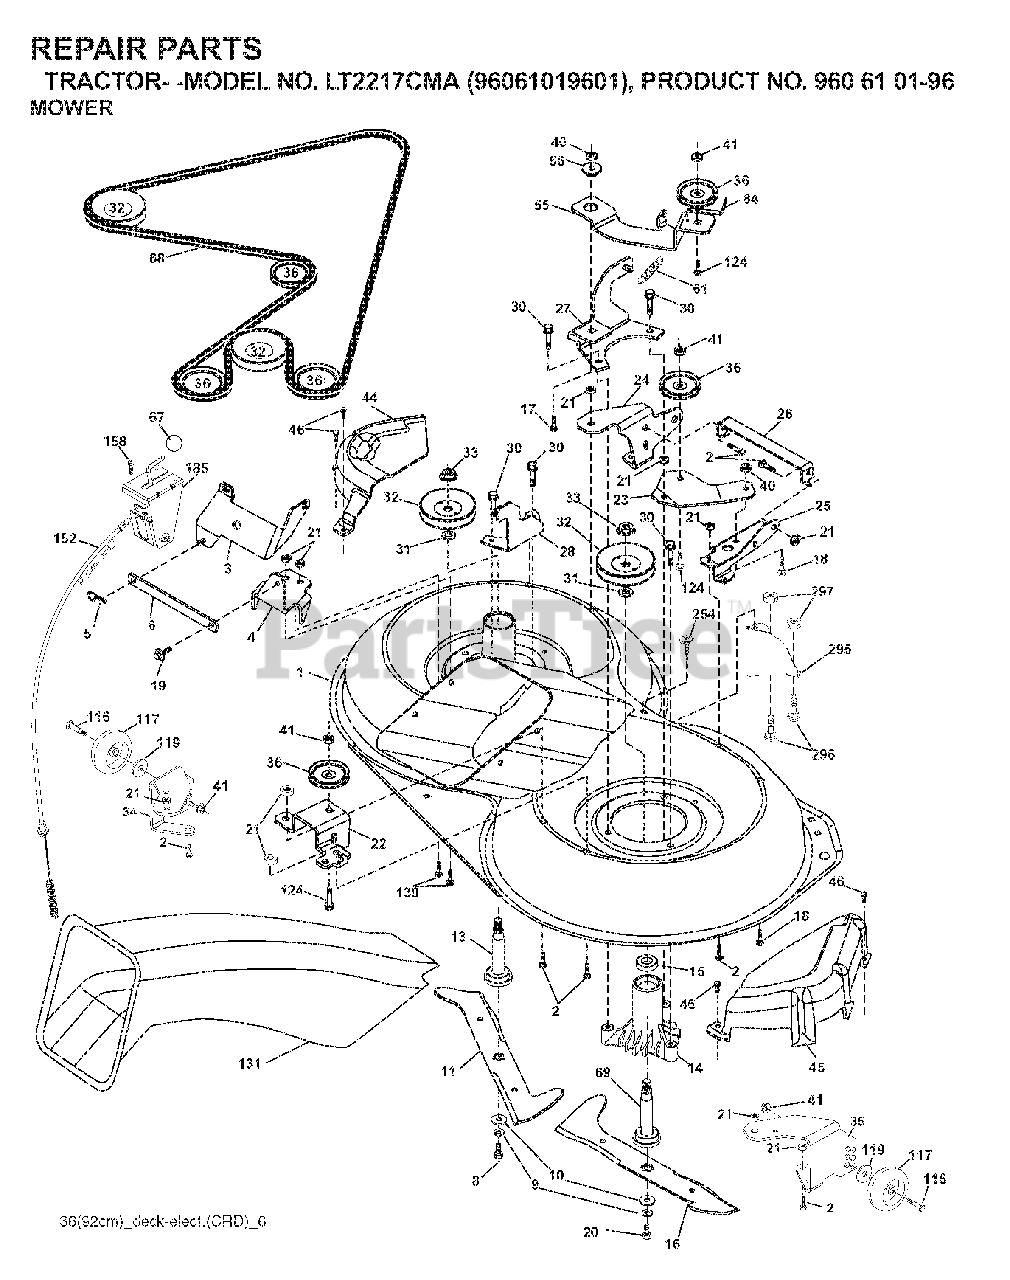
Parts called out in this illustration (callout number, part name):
2	BOLT
3	BRACKET
5	RETAINER-SPRNG RB
6	BAR SWAY
9	LOCKWASHER
10	WASHER.BLADE
13	SHAFT ASM VENT
14	HSG MANDREL
17	BOLT.3/8-14X1.25
19	BOLT SHD 5/16-18
21	LOCKNUT
24	BRACKET
25	BRACKET
28	BRACKET
30	SCREW, WASHER HEAD
31	WASHER.SPACER.MANDREL
32	PULLEY MANDREL
33	NUT.FLANGE.LOCK.TOP
36	PULLEY.IDLER.4.25
40	LOCKNUT
41	NUT LOCK FLG 3/8-16 UNC
45	MANDREL COVER
46	SCREW.1/4-20X5/8
56	SPACER.RETAINER.MOWER
67	KNOB T (3/8 HOLE)
69	SHAFT.ASM.W/LWR.BRG.RH.THREAD
84	KEEPER, BELT IDLER
116	BOLT.SHOULDER.3/8-16X3-5/8
117	WHEEL. GUAGE RALLY
118	NUT LOCK FLG 3/8-16 UNC
124	BOLT.3/8-16X1.50
131	CHUTE BAGGER
158	SCREW
185	HEAD ASM. CABLE CLUTCH
254	SCREW 3/8-16X1
296	BOLT
297	NUT CENTERLOCK
